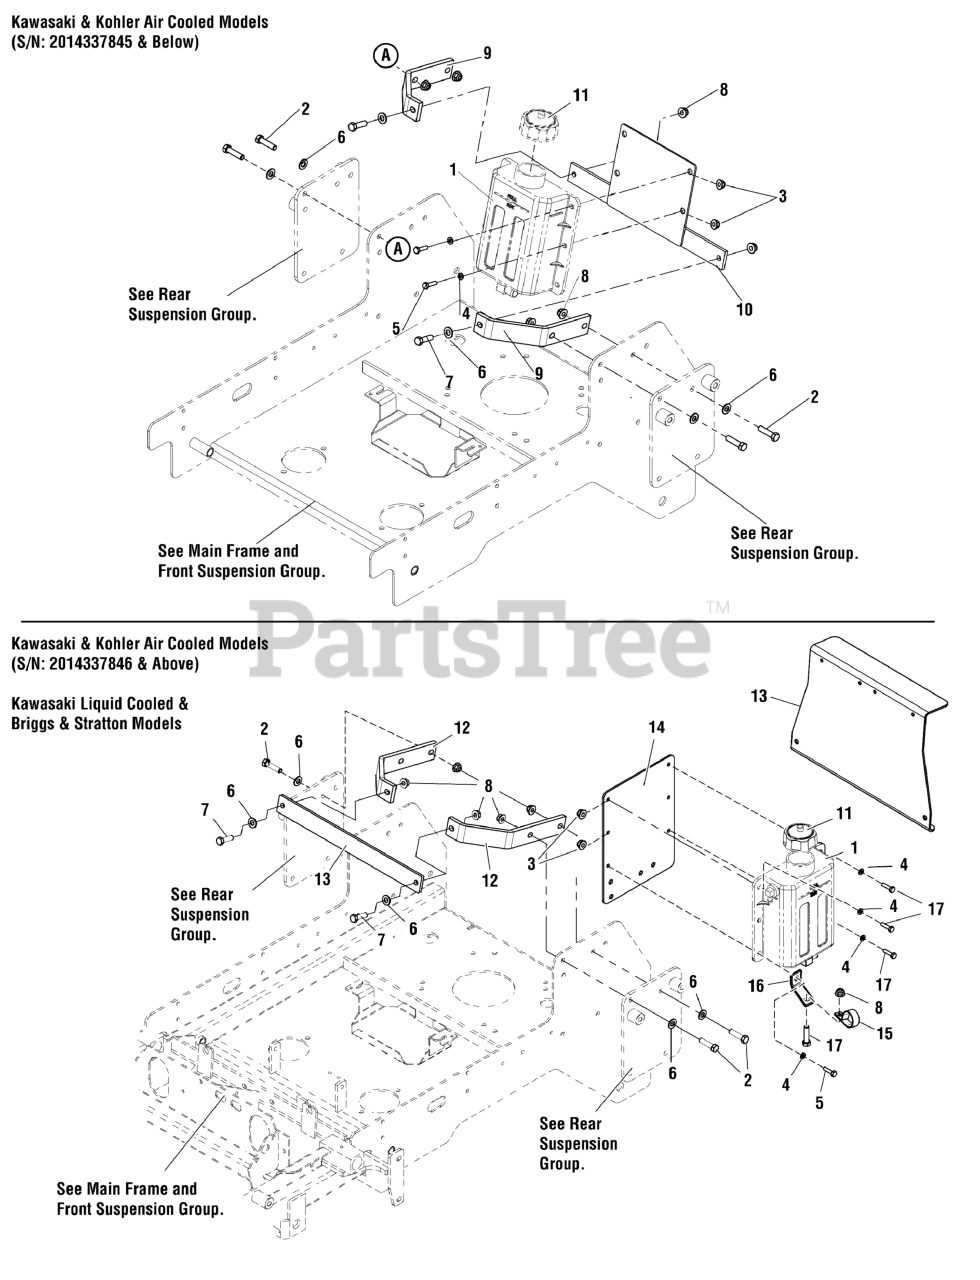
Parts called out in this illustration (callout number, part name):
1	TANK, HYDRAULIC, ASSEMBLY (See Hydraulic Group)
2	BOLT, 3/8-16 X 1-1/2" GD5 CZ
3	NUT, 1/4-20 HEX NYLOCK FLANGE
4	WASHER, 1/4 SAE
5	BOLT, 1/4-20 X 1" GD5 CZ
6	WASHER, 3/8 SAE
7	BOLT, 3/8-16 X 1-1/4" GD5 CZ
8	NUT, 3/8-16 HEX NYLOCK FLANGE
9	BRACKET, HYDRAULIC TANK
10	WELD, HYD TANK MOUNT - RED
11	CAP, HYDRAULIC (See Hydraulic Group)
12	BAR, STABILIZER, SIDE - RED
14	PLATE, HYDRAULIC TANK MOUNT - RED
15	CLAMP, VINYL INSULATED
16	BRACKET, HOSE - BLK
17	BOLT, 1/4-20 X 3/4" GD5
